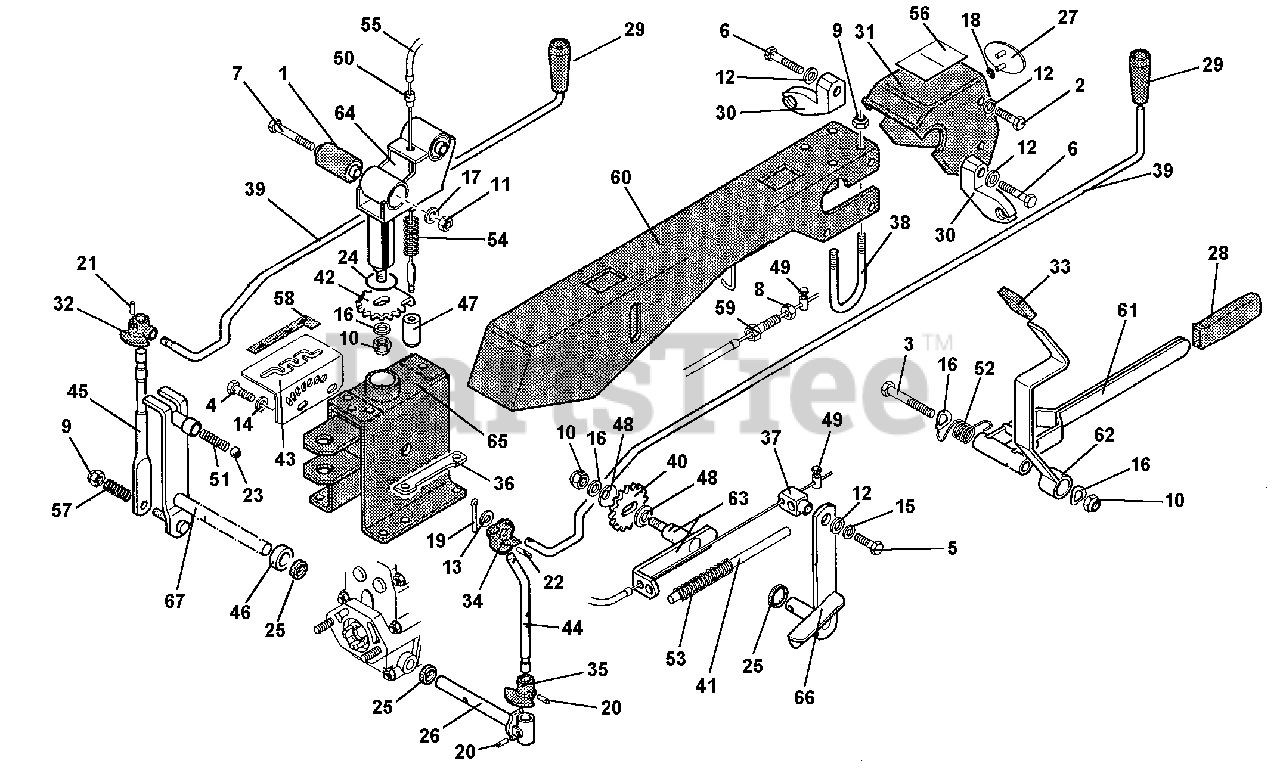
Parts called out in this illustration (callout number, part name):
1	SILENTBLOCK
2	SCREW, M8X16
3	SCREW, M10X90
4	SCREW, M8X14
5	SCREW, M8X12
6	SCREW, M8X35
7	SCREW, M12X95
9	NUT, SELF LOCKING, M8
10	NUT, SELF LOCKING, M10
11	NUT, SELF LOCKING, M12
12	WASHER, FLAT, M8.4
14	WASHER, M8.4
15	WASHER, LOCK, M8.4
16	WASHER, LOCK, M10.5
17	WASHER, LOCK, M13
18	WASHER, LOCK FOR PINS
20	LOCKING PIN, M4X20 SPIRAL
21	PIN, LOCKING, M3X22 SPIRAL
22	LOCKING PIN, M4X24 SPIRAL
23	BALL 15/32 RIV RB-11.906
24	O-RING, M28.17X3.53
25	OIL SEAL, M14X22X4
30	SUPPORT CONTROL ROD CUT
31	STEERING COLUMN INTERM. PANEL
32	GEARBOX ARTICULATION
33	KNOB REDUCTION UNIT LEVER
34	PTO ARTICULATION
35	PTO STOP RING
36	REVERSE SPEED LEVER DOG
37	REVERSE BLOCK
38	HANDLEBAR U-BOLT
39	GEARBOX CONTROL ROD
40	REVERSE GEAR
42	BENDED REVERSER GEAR
43	GEAR QUADRAINT
44	PTO CONTROL LEVER
47	PUSH ROD D=8
48	PROTECTION END D 32
49	CLAMP, CABLE
52	HANDLEBAR RELEASE SPRING
53	REVERSER SPRING
54	PUSH ROD SPRING
55	STEERING COLUMN CABLE
56	STEERING COLUMN STICKER
59	ADJUSTING SCREW
60	STEERING COLUMN
61	HANDLEBAR RELEASE LEVER
62	STEERING COLUMN LOCKING LEVER
63	REVERSER POSTION LEVER
64	STEERING COLUMN COUPLING
65	STEERING COLUMN SUPPORT
66	REVERSER LEVER
67	SPEED SELECTOR LEVER
